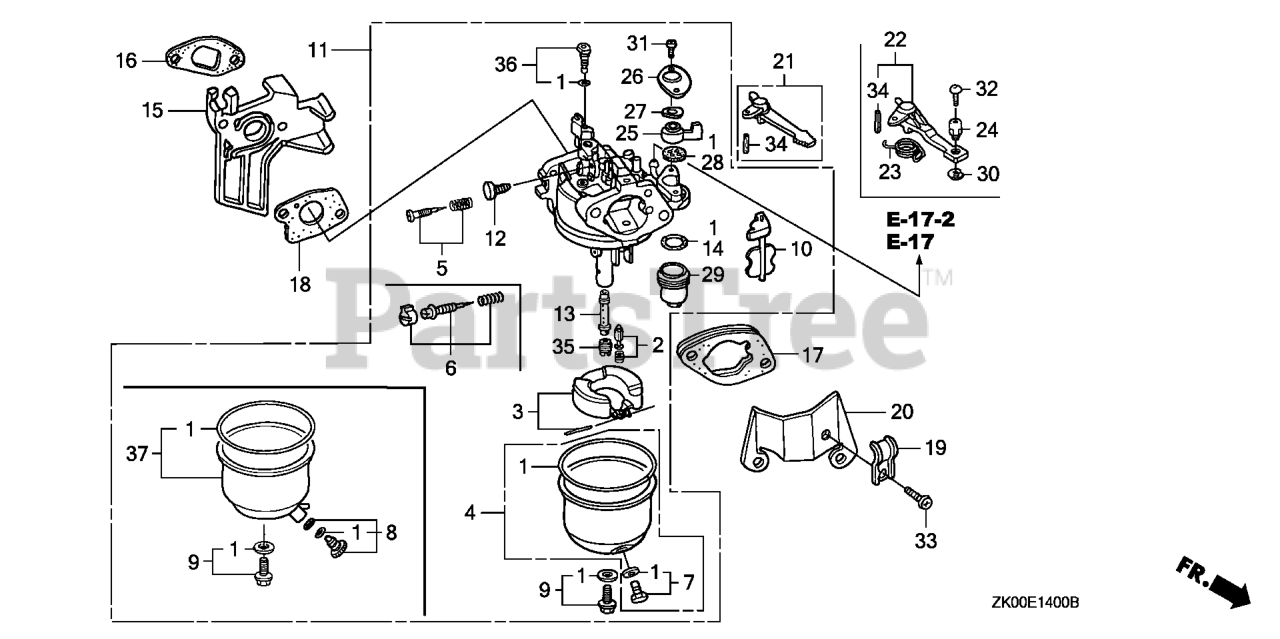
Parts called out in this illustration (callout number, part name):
1	GASKET SET
2	VALVE SET, FLOAT (CARBURETOR NO.) (SEAT NOT INCLUDED)
3	FLOAT SET
4	CHAMBER SET, FLOAT (CARBURETOR NO.)
6	SCREW SET (Honda Code 4219879). (CARBURETOR NO.)
7	SCREW SET, DRAIN (Honda Code 1672187). (CARBURETOR NO.)
9	SCREW SET B
9	SCREW SET
10	CHOKE SET
11	CARBURETOR ASSY. (BE64B B/C)
12	SCREW, THROTTLE STOP
13	NOZZLE, MAIN
14	GASKET, FUEL STRAINER CUP
15	INSULATOR, CARBURETOR
16	GASKET, INSULATOR
17	SPACER, CARBURETOR
18	GASKET, CARBURETOR
21	LEVER, CHOKE (STD)
25	LEVER, VALVE
26	PLATE, LEVER SETTING (CARBURETOR NO.)
27	SPRING, PETCOCK LEVER (CARBURETOR NO.)
28	GASKET, VALVE
29	CUP, FUEL STRAINER
31	SCREW, PAN (3X6)
34	PIN, SPRING (2X12)
35	JET, MAIN (#72) (CARBURETOR NO.)
35	JET, MAIN (#68)
35	JET, MAIN (#70)
36	JET SET, PILOT (#45)
